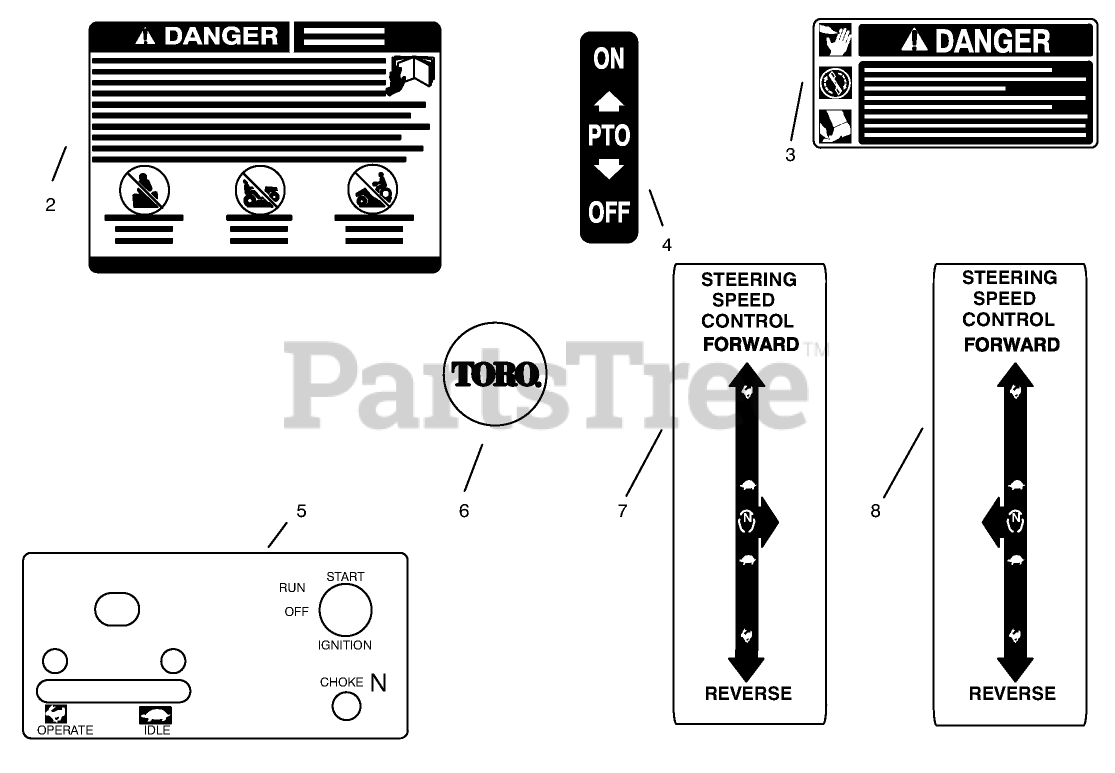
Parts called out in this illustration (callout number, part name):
2	DECAL-DANGER
3	DECAL-DANGER
4	DECAL-PTO
5	DECAL-CONTROL
6	NAME-PLATE TORO LOGO
7	DECAL-LH STRG SPD CONT
8	DECAL-RH STRG SPD CONT
